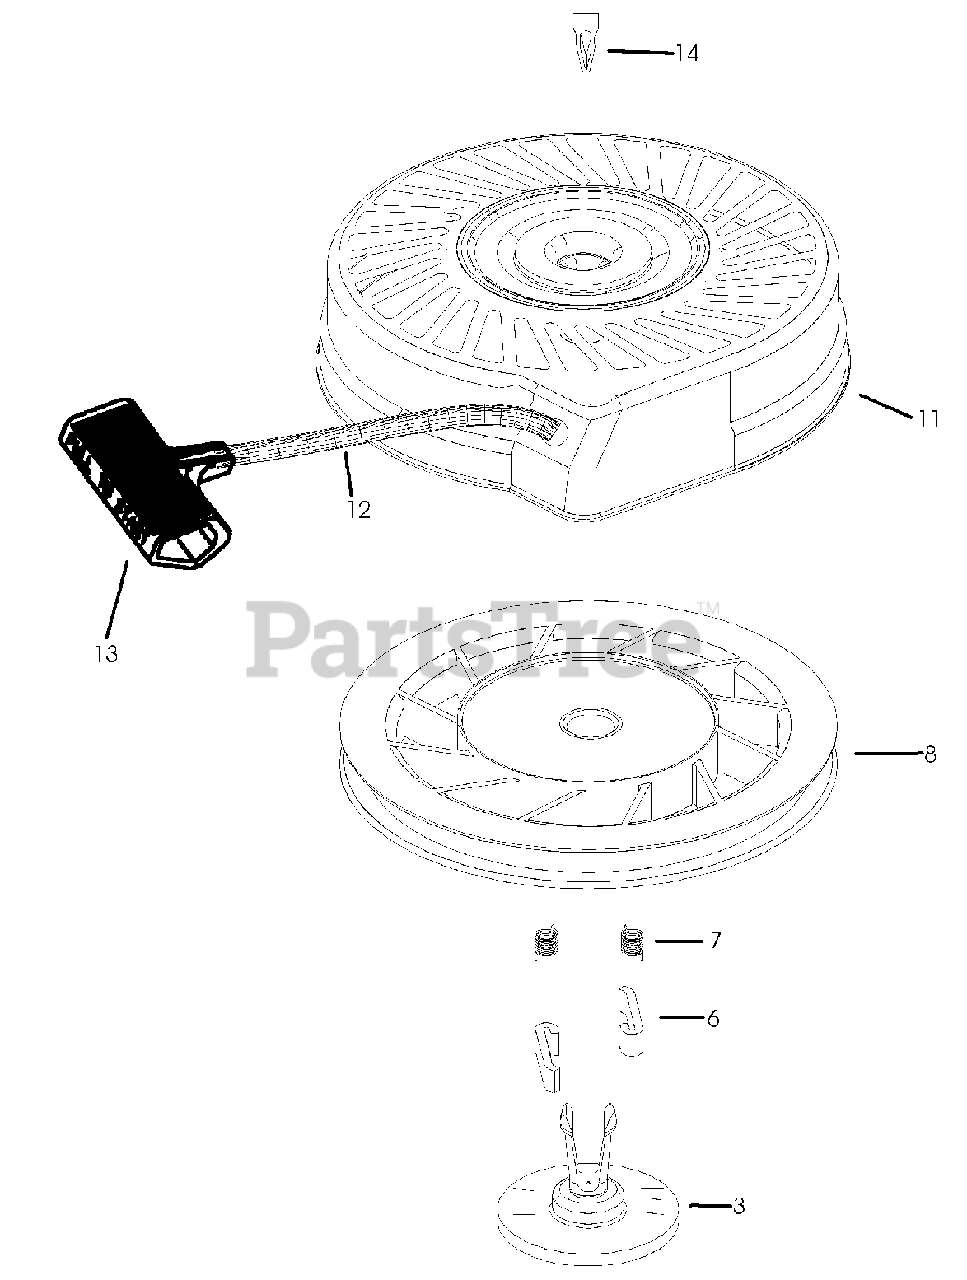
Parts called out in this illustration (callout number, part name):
3	Retainer
6	Starter Dog
7	Dog Spring
8	Pulley & Rewind Spring ASM
11	Starter Housing ASM (40 degree grommet)
12	Starter Rope (Length 98" x 9/64" dia.)
13	Starter Handle
14	Spring Clip
